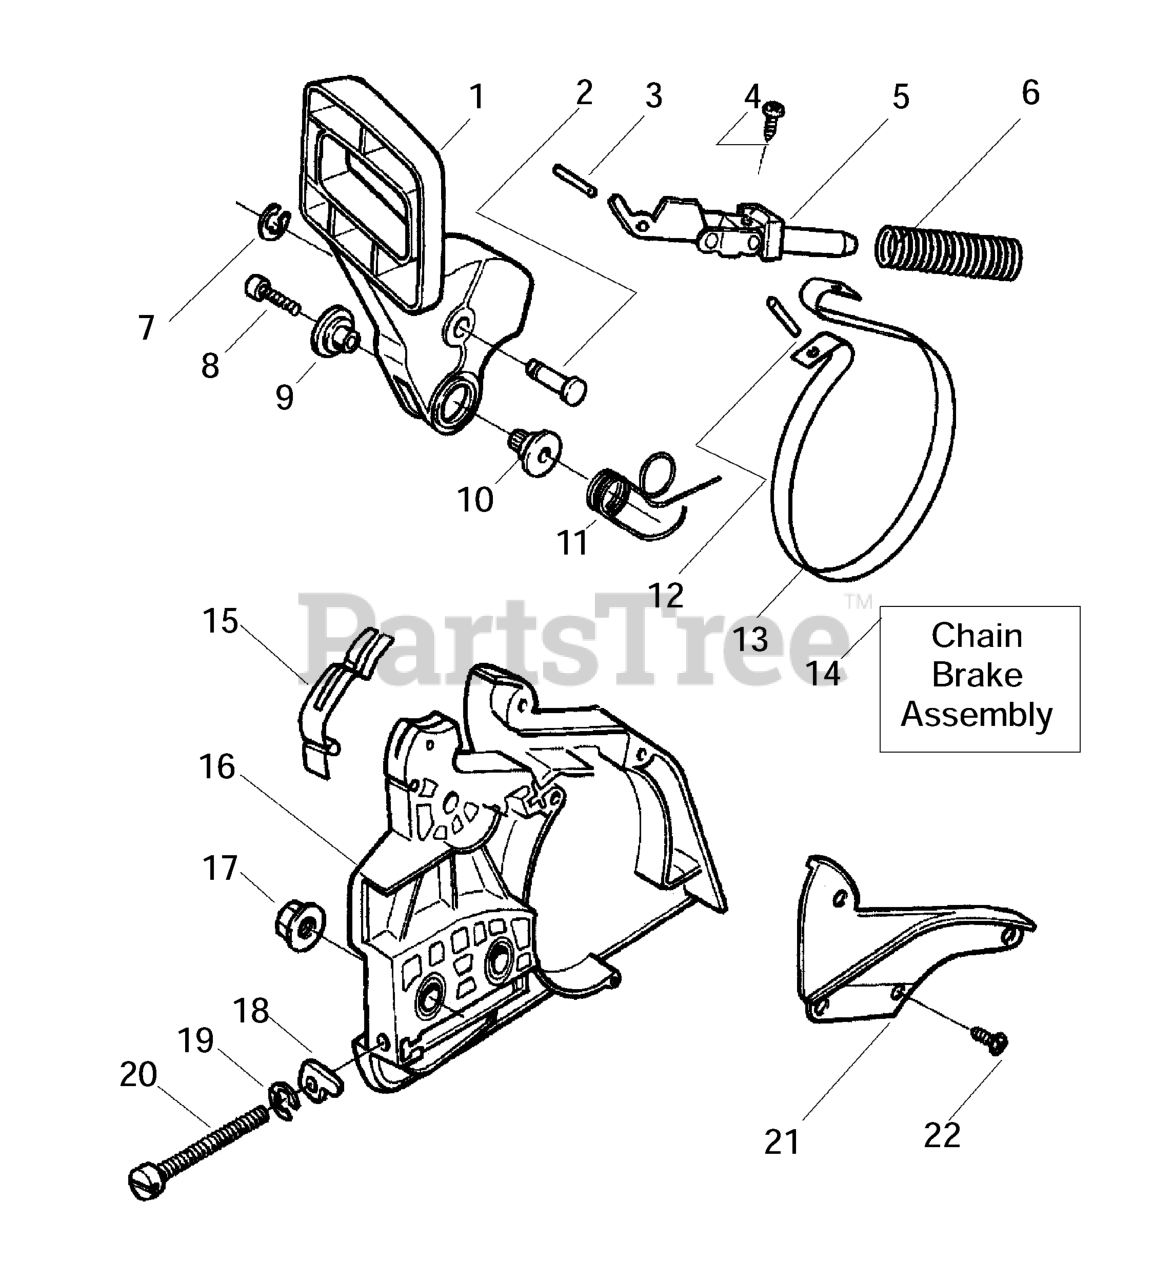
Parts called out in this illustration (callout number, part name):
4	SCREW
5	FRONT LINK ASSY
6	%COMPRESSION SPRING
9	JOURNAL, RIGHT
10	SHAFT PIVOT
11	SPRING,BRK HDL 36/41
13	BRAKE BAND
14	CHAIN BRAKE ASM.
15	SPRING-POSITION
16	CLUTCH COVER
18	ADJUST PIN,BAR 36/41
20	BAR ADJUSTING SCREW
21	CHAIN BRAKE COVER
22	SCREW
